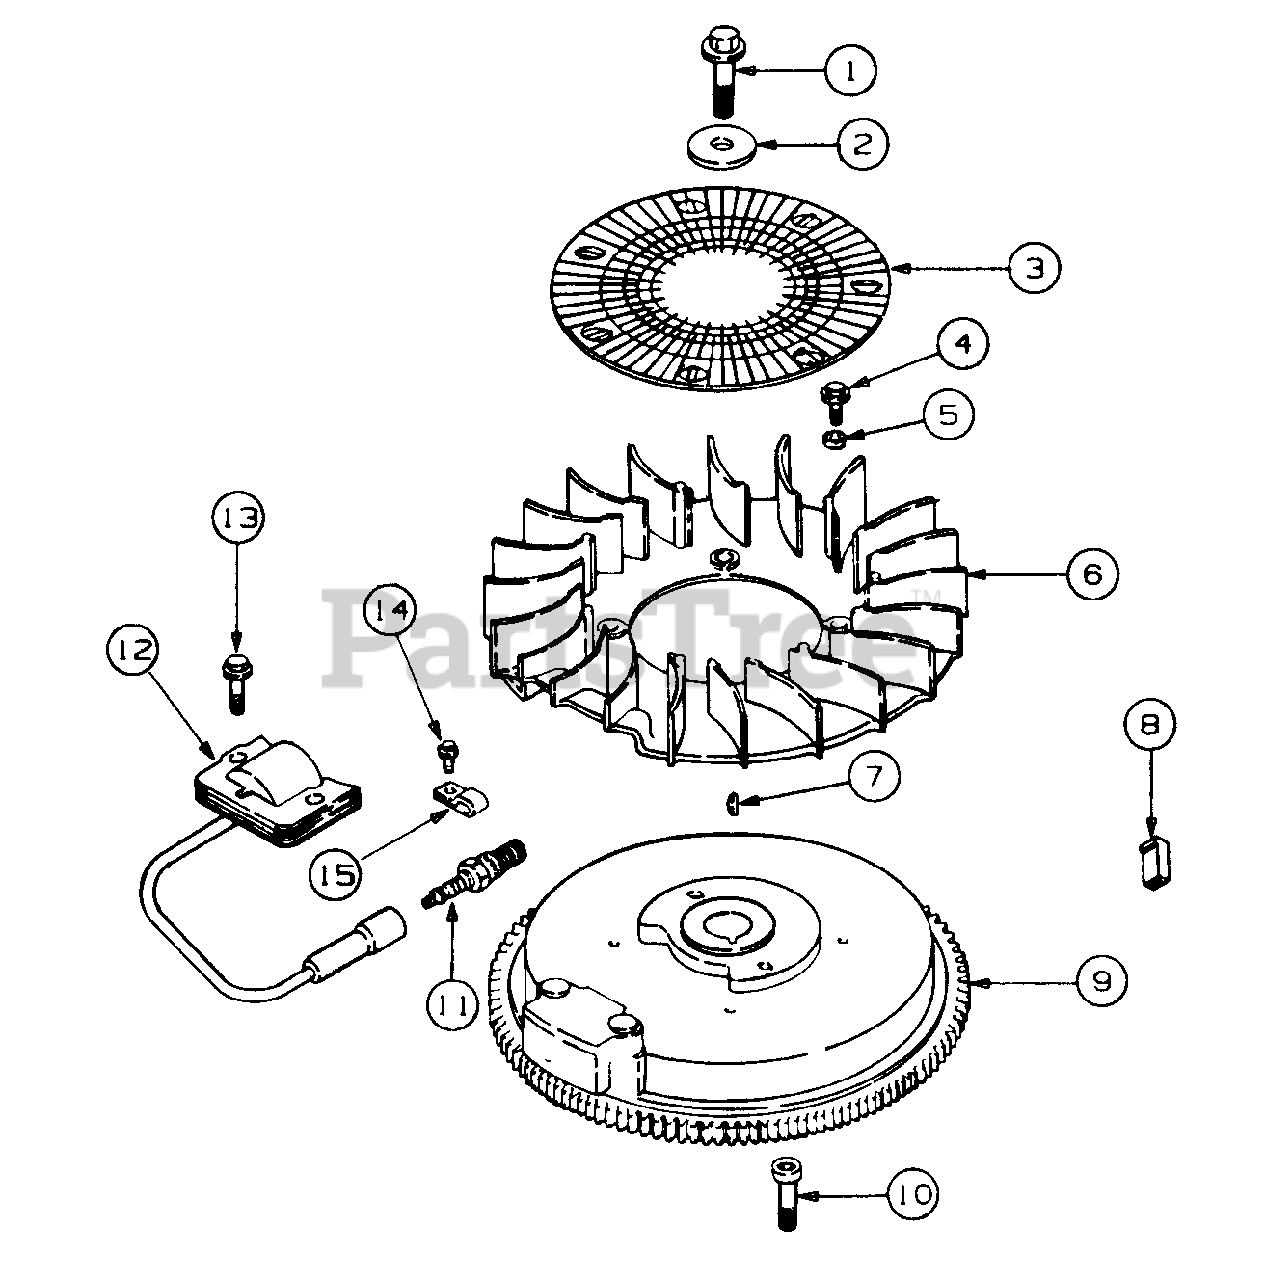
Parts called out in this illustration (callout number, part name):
1	Screw, Flywheel Mounting
2	Washer, Flywheel Screw
3	Screen, Grass
4	Screw, Fan Mounting
5	Spacer, Fan
6	Fan
9	Flywheel Assy
10	Screw, Hex Wash Hd
11	Spark Plug
12	Module, Ignition
13	Screw, Ignition Module, M5 X 0.8 X 20
14	Screw, Lead Clip
